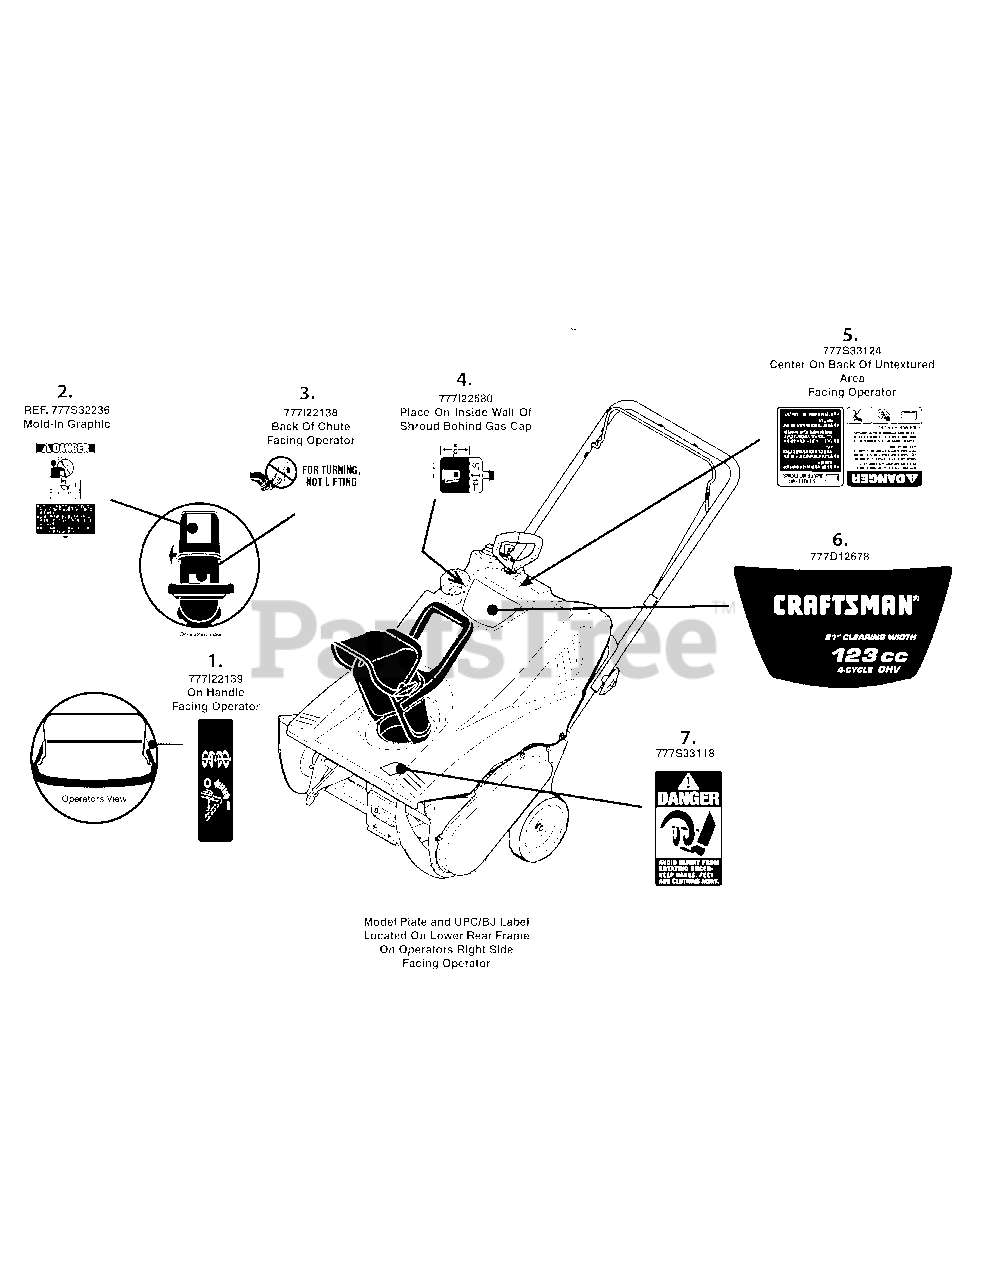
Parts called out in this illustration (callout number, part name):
1	LABEL-SNOW:HANDLE
2	LABEL-SNOW CHUTE
3	LABEL-CHUTE
4	LABEL-SNOW:FUEL LEVEL MAX
5	LABEL-SNOW HOUSING DANGER
6	LABEL-SNOW:SS 2M HOUSING:CRAFTSMAN
7	LABEL-SNOW FRONT AUGER DANGER
